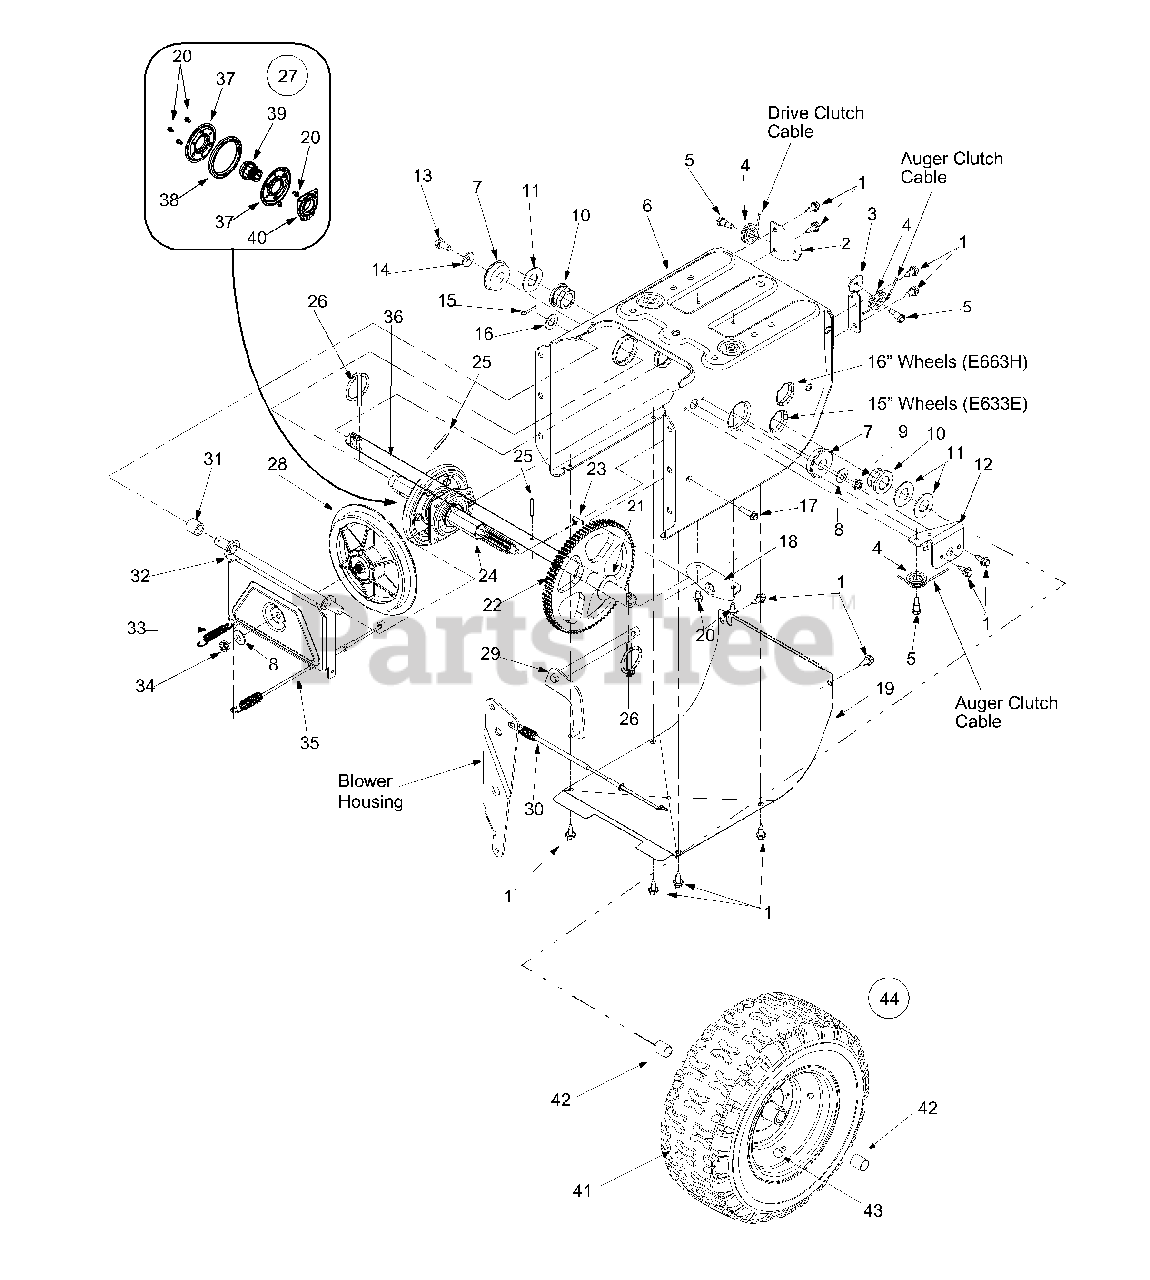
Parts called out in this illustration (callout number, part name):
1	Hex Screw
5	Hex Screw 1/4-28
8	Bell Washer
9	Lock Jam Nut
10	Hex Flange Bearing
11	Flat Washer
14	Bell Washer .340 ID x .872 OD
15	Cotter Pin
16	Flat Washer .536 ID x .930 OD
17	Hex Washer Screw 1/4-20
21	Flat Washer .760 ID x .50 OD
24	7-Tooth Shaft
25	Roll Pin
26	Clik Pin
27	Friction Wheel Assembly
28	Friction Disc Wheel
29	Wheel Shift Rod Assembly
30	Drive Cable
31	Spacer
34	Jam Nut, 3/8-24
35	Drive Cable
36	Axle 16" Wheels
39	7-Tooth Shaft
40	Friction Wheel Bearing
41	Tire Only, 16 x 6.5
42	Sleeve Bearing
43	Air Valve
